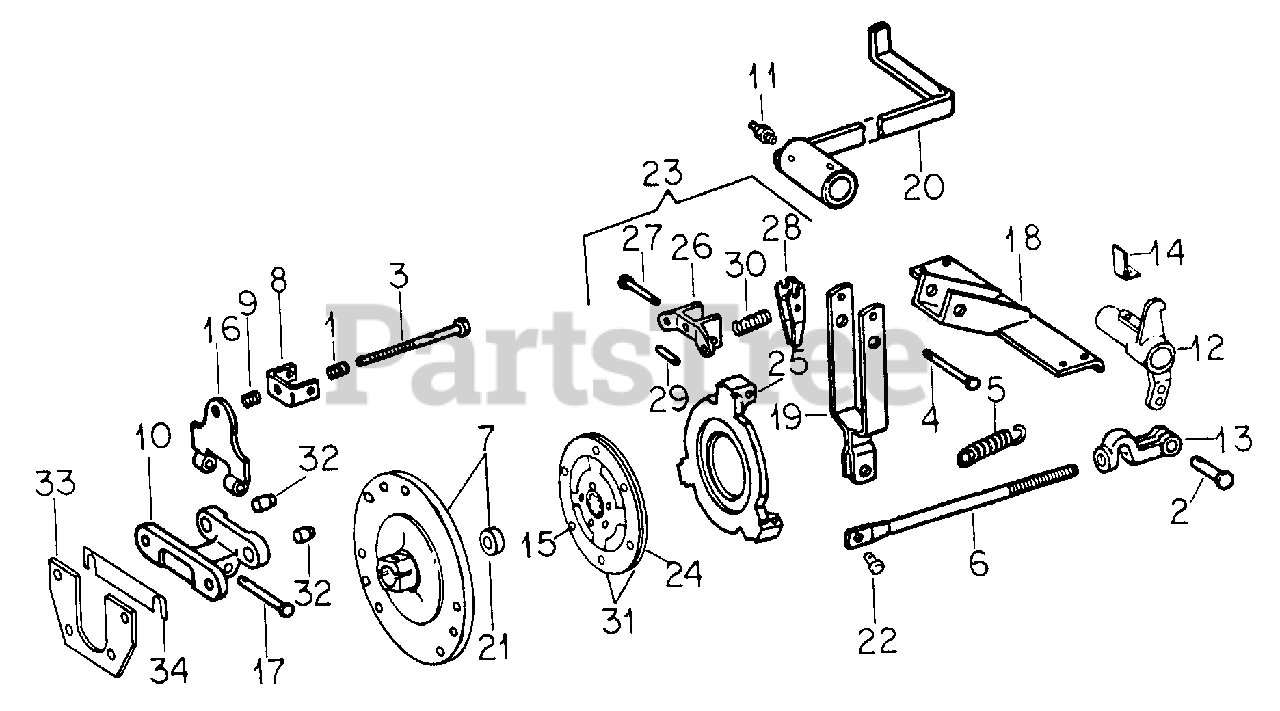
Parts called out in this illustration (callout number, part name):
1	SPRING, CLUTCH BRAKE TEASER
2	PIN, CLUTCH ROD ADJUSTABLE YOKE
3	BOLT, CLUTCH BRAKE
4	PIN, CLUTCH BRAKE YOKE
5	SPRING, CLUTCH RETURN
6	ROD, CLUTCH OPERATING
7	PLATE ASSY, PRESSURE
8	YOKE, CLUTCH BRAKE
9	SPRING, CLUTCH BRAKE STABILIZER
10	RETAINER, CLUTCH BRAKE
11	FITTING, 1/8-27 PTF STR LUBRICATION
12	LEVER, CLUTCH PEDAL
13	YOKE, CLUTCH ROD ADJUSTING
14	STRIP, SAFETY SWITCH RELEASE LEVER
15	RIVET, CLUTCH FACING
16	ARM ASSY, BRAKE
18	BRACKET ASSY. CLUTCH RELEASE
19	YOKE ASSY, CLUTCH RELEASE
20	PEDAL ASSY, CLUTCH
21	BUSHING, PRESSURE PLATE
22	PIN, CLUTCH ROD END
23	PLATE ASSY, CLUTCH PRESSURE
24	DISC W/FACINGS ASSY, CLUTCH DRIVEN
25	PLATE, PRESSURE
26	BRACKET, LEVER
27	PIN, LEVER PIVOT
28	LEVER, RELEASE
29	PIN, PRESSURE PLATE
30	SPRING, PRESSURE
31	PACKAGE CLUTCH FACING
32	LINING ASSY, BRAKE
33	BRACKET, CLUTCH BRAKE
34	SPACER, CLUTCH BRAKE RETAINER
